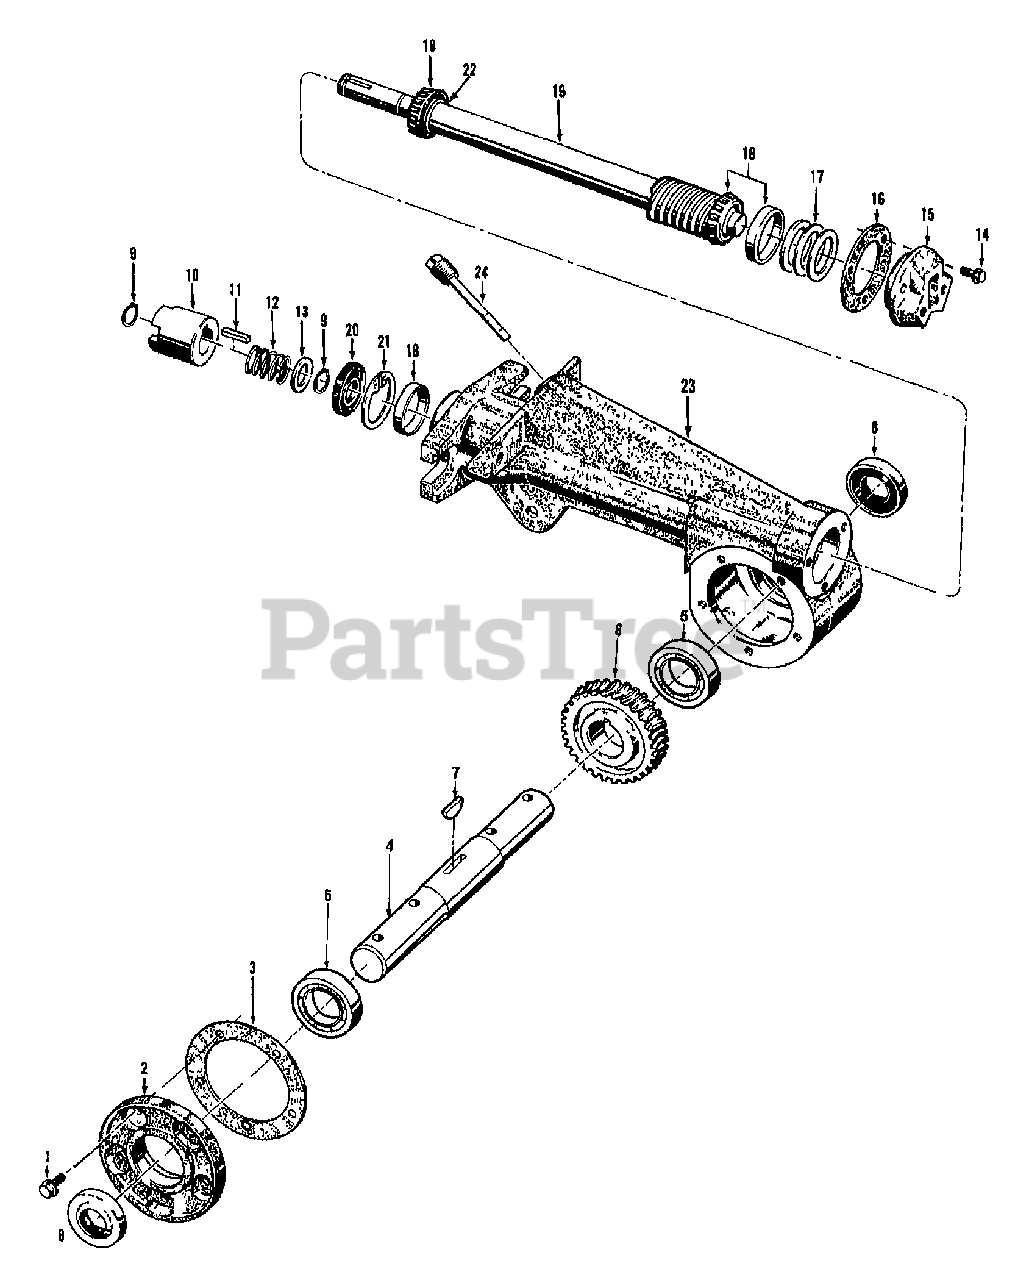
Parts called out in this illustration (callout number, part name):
1	KIT-SEALING SCRS (5)W/LIT
2	COVER-TILLER HSG MACH
3	GASKET-TILLER COVER
4	SHAFT-TILLER MACH HORSE
5	BEARING-BALL
6	GEAR-WORM MACH RTH HORSE
7	KEY-WOODRUFF .25X1.12
8	SEAL-TILLER SHAFT
9	RING-RETAIN EXT .707 ID
10	KIT-CLUTCH DOGS TILLER
10	CLUTCH-DOG HORSE TRANS
11	KEY-.188 SQX1.0
12	SPRING (TC)
13	SHIM-1.0X.7656X.062
14	KIT-SEALING SCRS (3)
15	CAP-REAR #1115
16	GASKET-BRG COVER
17	SHIM-1.75X1.5X.01
17	SHIM-1.75X1.5X.03
17	SHIM-1.75X1.5X.005
17	SHIM-1.75X1.5X.062
18	KIT-BRG CONE&RACE-DRIVESHAFT
19	KIT-TILLER DR SHAFT
20	SEAL-OIL DRIVESHAFT
21	RING-RETAINING 5000-181
22	SHIM-1.0X.7656X.062
23	HOUSING-TILLER W/SLEEVE
24	ASSM-DIPSTICK HORSE TRANS
